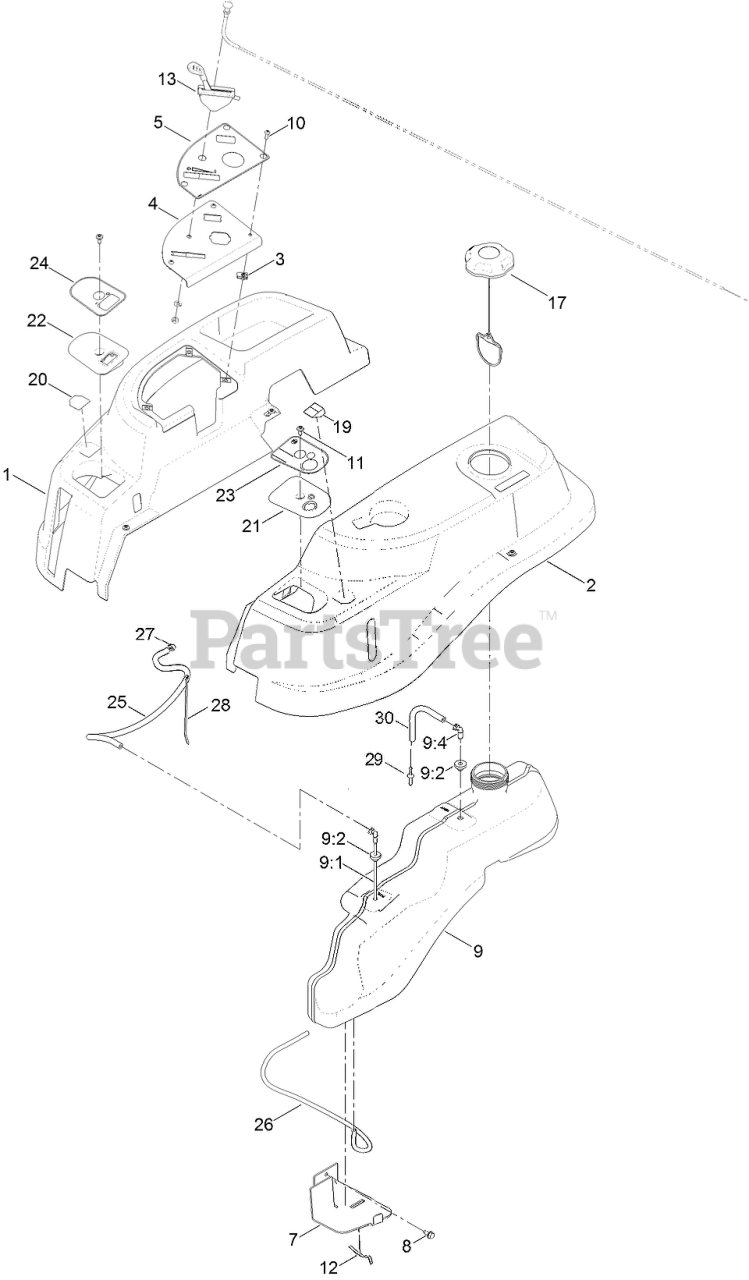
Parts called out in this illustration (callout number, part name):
1	POD-RH
2	POD-LH
4	PLATE-CONTROL
5	DECAL-PANEL, CONTROL
7	SUPPORT-TANK, FRONT
8	SCREW-HWHTF
9	FUEL TANK ASM
9:1	CONNECTOR-ELBOW, 90 DEG
9:2	BUSHING
9:4	FITTING-PLASTIC
10	SCREW-PRH
11	SCREW-SHOULDER
12	SPRING
13	CABLE-THROTTLE AND CHOKE
17	CAP-FUEL, RATCHETING
19	DECAL-NMIR
20	DECAL-CONTROL, PEDAL
21	COVER-LH
22	COVER-RH
23	DECAL-KEYCHOICE
24	DECAL-BRAKE, PARKING
25	HOSE-FUEL
26	HOSE-FUEL
27	CLAMP-HOSE
28	TIE-CABLE
29	ADAPTOR-ORIFICE
30	HOSE-FUEL
